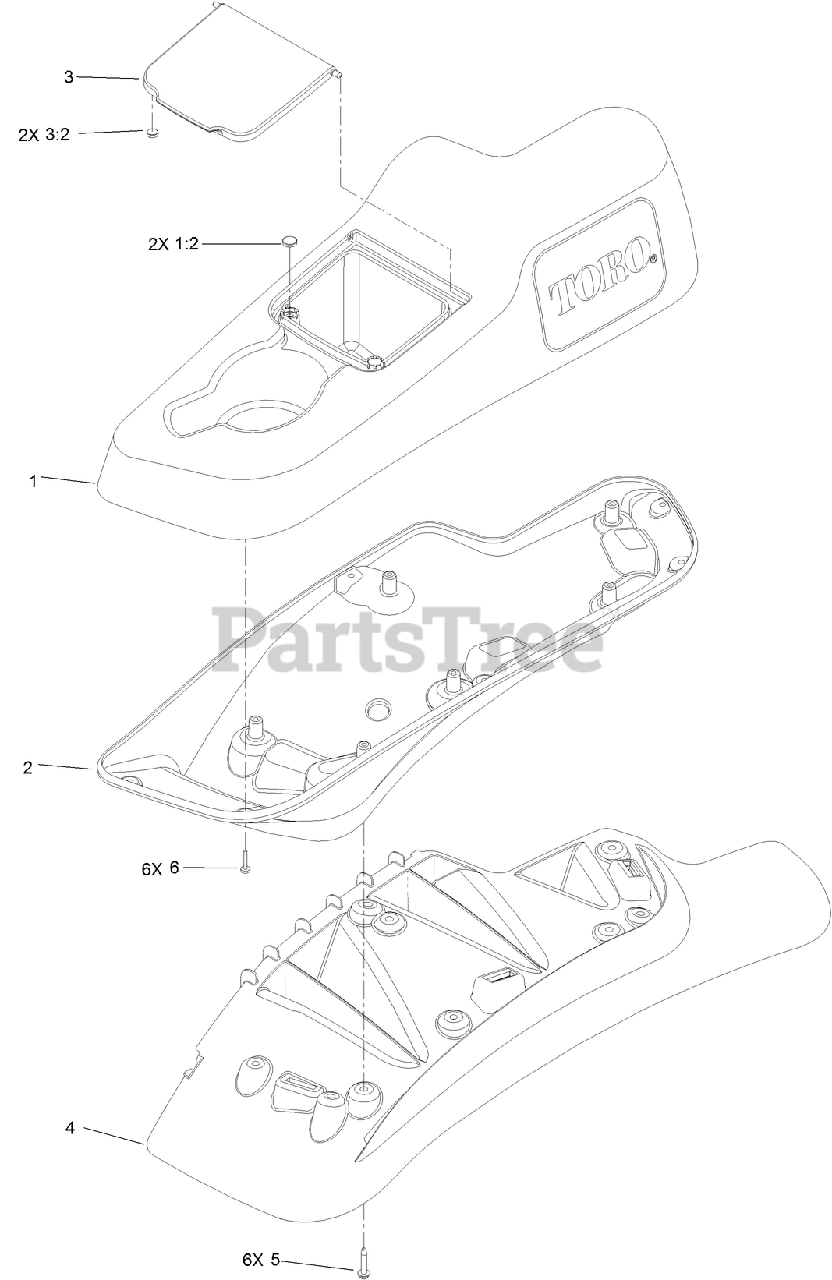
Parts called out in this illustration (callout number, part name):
1	LH CONSOLE TOP ASM
2	LH LOWER CONSOLE ASM
3	LID ASM
3:2	MAGNET
4	FENDER-LH
5	SCREW-THREAD FORMING
6	SCREW-PPH
